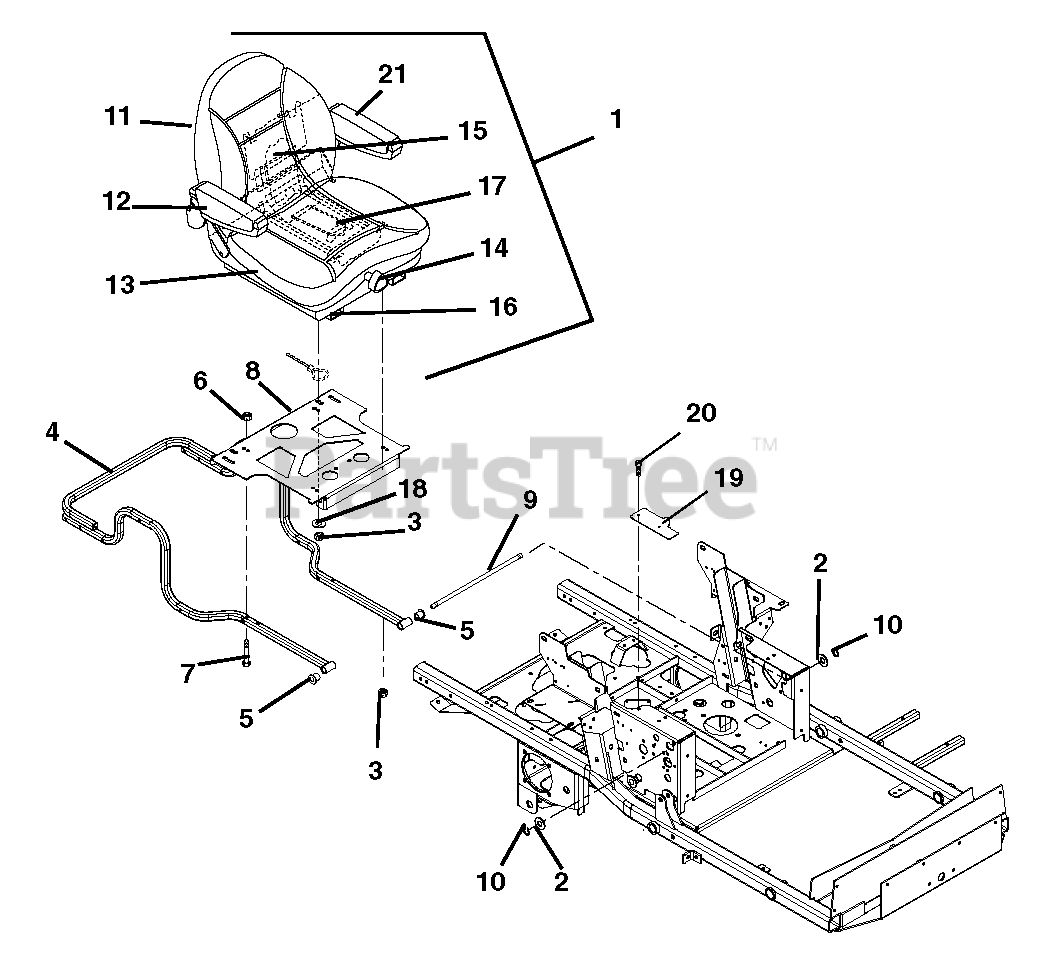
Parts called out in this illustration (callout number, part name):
1	Seat, Suspension, Light Gray
2	Washer, Flat Steel .531 x 1.06 x .095
3	Nut, Locking Top Flange .31-18
4	Weldment, Hood Frame
5	Bushing-Flange .515 x .750 x .745 x 1.00
6	Nut, Locking Top Flange .38-16
7	Bolt, Rib Neck .38-16 x 1.50
8	Weldment, Seat Pivot Mount
9	Rod, Seat Frame Pivot
10	Ring, Retaining External .500 x .050
11	Kit, Back Cushion, Light Gray
12	Kit, Right Hand Armrest Assembly
13	Kit, Seat Cushion, Light Gray
14	Kit, Seat Knobs
15	Kit, Seat Back
16	Kit, Seat Slides
17	Kit, Seat, Spring and Saddle
18	Washer, Flat Steel .344 x 1.25 x .135
19	Plate, Block Off
20	Screw, Tapping .25-20 x .75 Hex Washer Head
21	Kit, Left Hand Armrest Assembly
